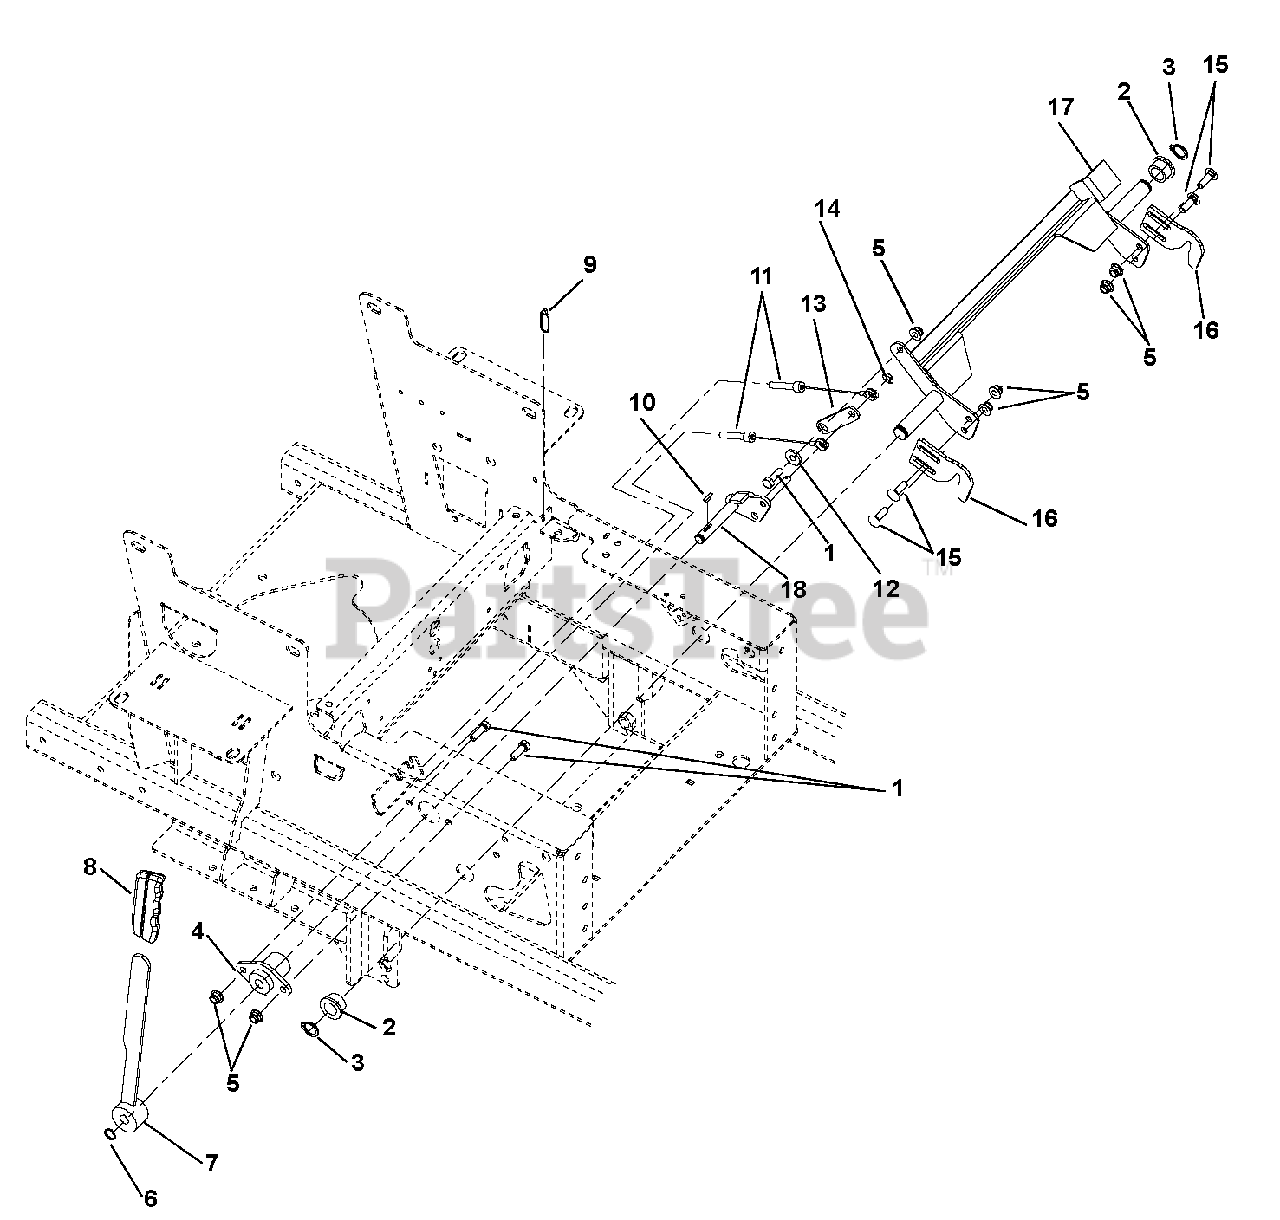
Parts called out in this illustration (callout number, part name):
1	Bolt, Hex .31-18 x 1.00
2	Bushing, Flange .750 x 1.000 x .625 x 1.250
3	Ring, Retaining External .689 x .077
4	Bushing, Flanged
5	Nut, Nyloc Flange .31-18
6	Ring, Retaining External .500 x .050
7	Weldment, Parking Brake Arm
8	Grip, Parking Brake
9	Cable Tie
10	Key, Woodruff .13 x .63 HRD #5
11	Cable, Brake Actuating
12	Bushing, Flange .325 x .499 x .26 x .88
13	Plate, Neutral Interlock
14	Nut, Push .312
15	Bolt, Round Head Square Neck .31-18 x 1.00
16	Neutral Lock Latch
17	Weldment, 100I Neutral Lock
18	Weldment, Park Brake Arm
